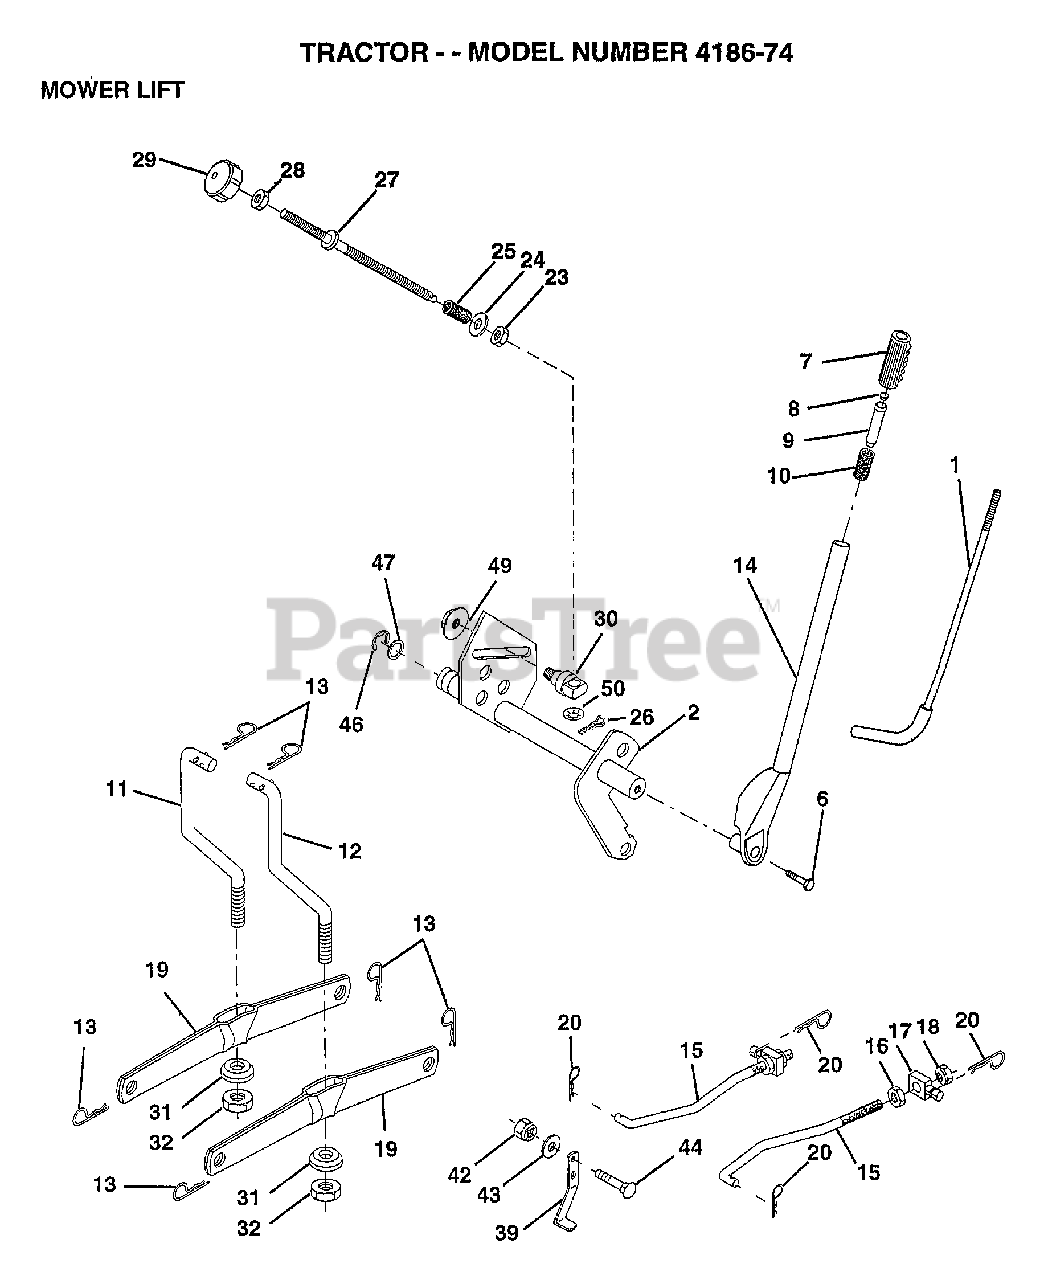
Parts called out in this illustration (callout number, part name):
1	LEVER ROD LT
2	SHAFT LIFT W/IND
6	"BOLT,HEX"
7	GRIP
10	SPRING T
11	LINK.LIFT.LH.GTV
12	LINK.LIFT.RH.GTV.
15	LINK.FRONT
16	NUT
17	TRUNION
18	NUT.LK.W/WSH.1/2.
19	ARM SUSP REAR
20	RETAINER.SPRING
23	NUT T
24	WASHER
25	SPRING.COMP.INF.H
27	ROD.ADJ.LIFT
28	NUT
29	KNOB INF 3/8-16
30	TRUNNION
31	BEARING PVT LH
32	NUT.CROWNLOCK.3/8
39	STOP.OVER.CENTER
43	WASHER GT
44	BOLT
46	E-RING
47	WASHER
49	NUT.HXFLG.LOCK.
50	NUT PUSH M
